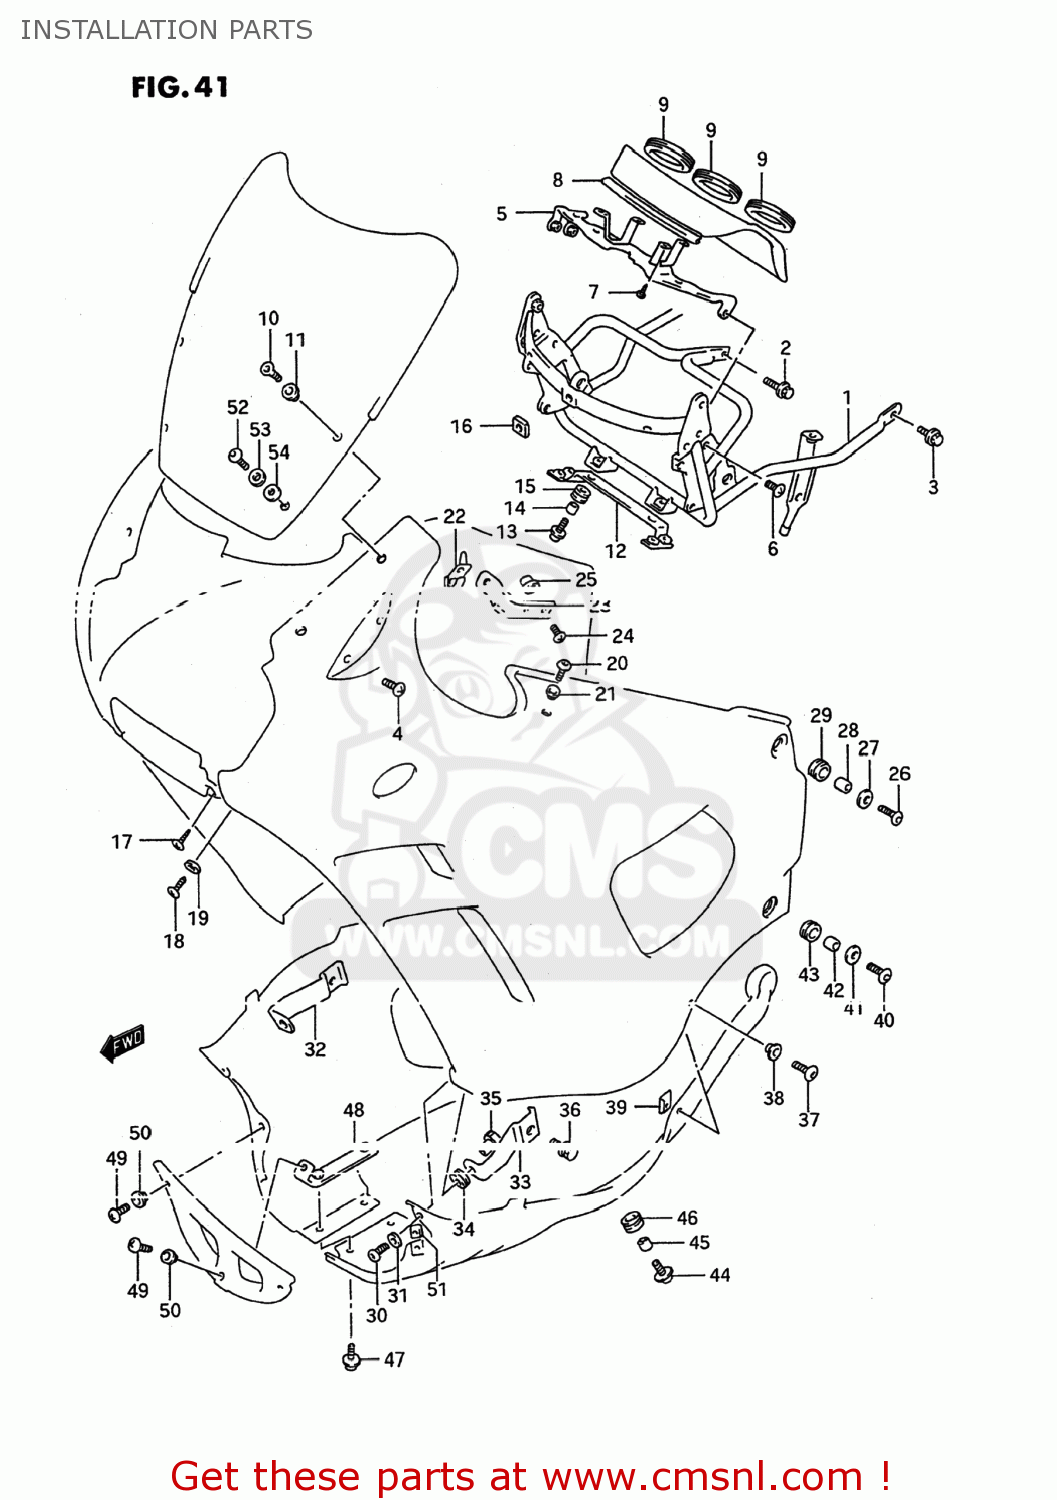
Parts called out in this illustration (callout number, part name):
1	BRACE,COWLING
2	BOLT
3	BOLT
4	SCREW 6X12
5	PLATE,METER FITING
6	SCREW 6X12
7	SCREW 5X8
8	MOLDING,METER COVER
9	CUSHION,METER COVER
10	SCREW
11	WASHER(5.2X11X1)
12	PLATE,COWL CTR PANEL
13	SCREW(6X20)
14	SPACER (6,8X10X9.4)
15	CUSHION
16	CUSHION,SCREEN
17	SCREW
18	SCREW(6X25)
19	WASHER(6.5X18X1.5)
20	SCREW(6X16)
21	WASHER(6.3X16X1.5)
22	BRACKET,COWLING UPR,R
23	BRACKET,COWLING UPR,L
24	SCREW
25	NUT,COWLING SIDE BRKT
26	SCREW(6X25)
27	WASHER(6.5X18X1.5)
28	SPACER (6.1X9X9)
29	CUSHION
30	SCREW(6X30)
31	WASHER(6.5X18X1.5)
32	BRACKET,COWLING LWR,R
33	BRACKET,COWLING LWR,L
34	CUSHION
35	NUT,COWLING,FR
36	BOLT
37	SCREW(5X14)
38	WASHER(5.2X14X1.5)
39	NUT,HEADLAMP HOUSING,UPPER
40	SCREW(6X25)
41	WASHER(6.5X18X1.5)
42	SPACER(6.1X9X12.3)
43	CUSHION
44	SCREW(6X20)
45	SPACER (6.1X9X9)
46	CUSHION
47	SCREW
48	BRACKET,FR UNDER COWL
49	SCREW
50	WASHER(5.2X14X1.5)
51	NUT,HEADLAMP HOUSING,UPPER
52	SCREW
53	WASHER
54	WASHER
